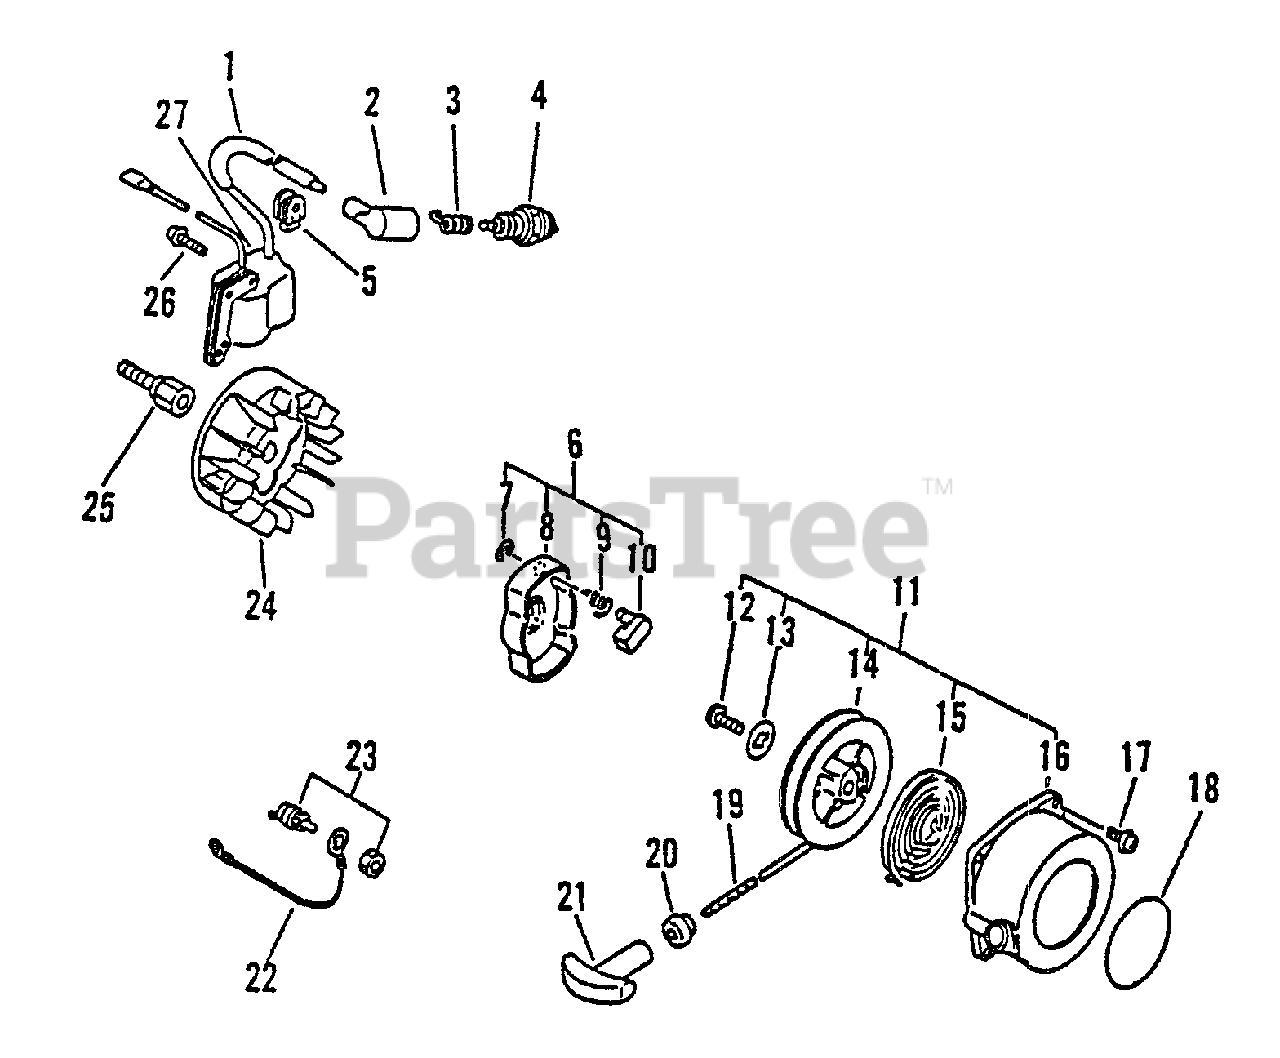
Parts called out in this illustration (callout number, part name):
2	CAP, SPARK PLUG
3	TERMINAL, SPARK PLUG
4	SPARK PLUG - BPM7A
6	STARTER PAWL ASSY
7	E-RING 4
8	CATCHER, PAWL
9	SPRING, RETURN
10	PAWL, STARTER
11	STARTER ASSY
13	WASHER
14	REEL, ROPE
15	SPRING, RECOIL
16	CASE, RECOIL STARTER
17	SCREW 4×18
19	ROPE, STARTER
20	GUIDE, ROPE
21	GRIP, STARTER
22	LEAD - GROUND
23	SWITCH, ON-OFF
24	FLYWHEEL
25	HUB, FAN
26	SCREW 4×22
27	COIL, IGNITION
